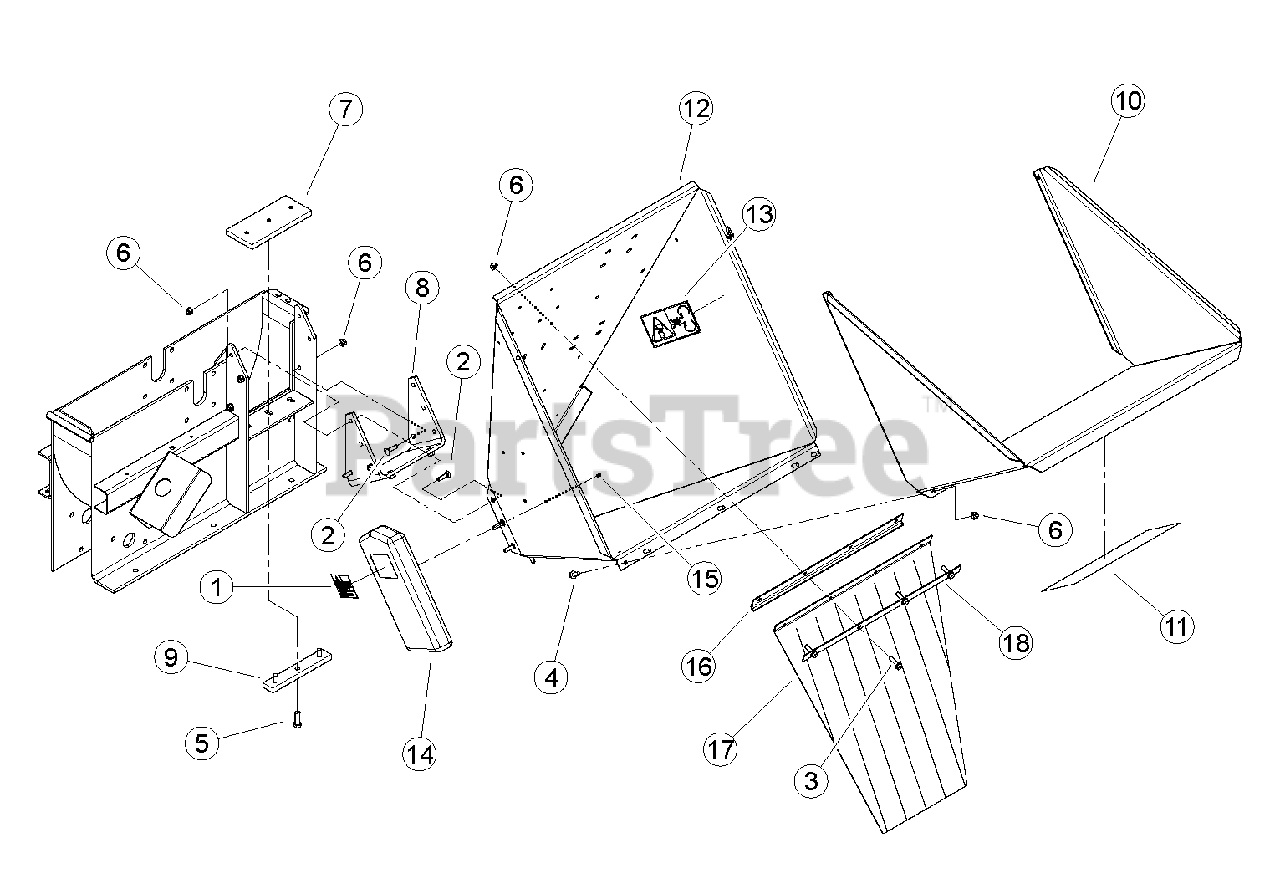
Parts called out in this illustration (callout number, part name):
1	DECAL, MUTILINGUAL MANUAL
2	BOLT, 3/8 X 1-1/2" GR5 NC ZP
3	BOLT, 3/8 X 1-1/4 FLANGE NC
4	BOLT, 3/8 X 1 FLANGE NC
5	BOLT, 1/2 X 1-1/2 GR8 NC ZP HEX HD
6	NUT, 3/8-16 NYLOCK FLANGE
7	PLATE, CHIPPER BOTTOM
8	BASE, CHIPPER CHUTE
9	SPACER, CHIPPER ANVIL
10	ASSEMBLY, CHUTE EXTENSION (CE COMPLIANT ONLY)
11	DECAL, BEARCAT WEB
12	ASSEMBLY, CHIPPER CHUTE
13	DECAL, BLADE DANGER ISO
14	CONTAINER, INSTR. MANUAL
15	RIVET, 1/4 X 1/2 DOME HD BLIND SS
16	ANGLE, FLAP ANCHOR
17	FLAP, CHIPPER CHUTE
18	STRIP, FLAP RETAINER
